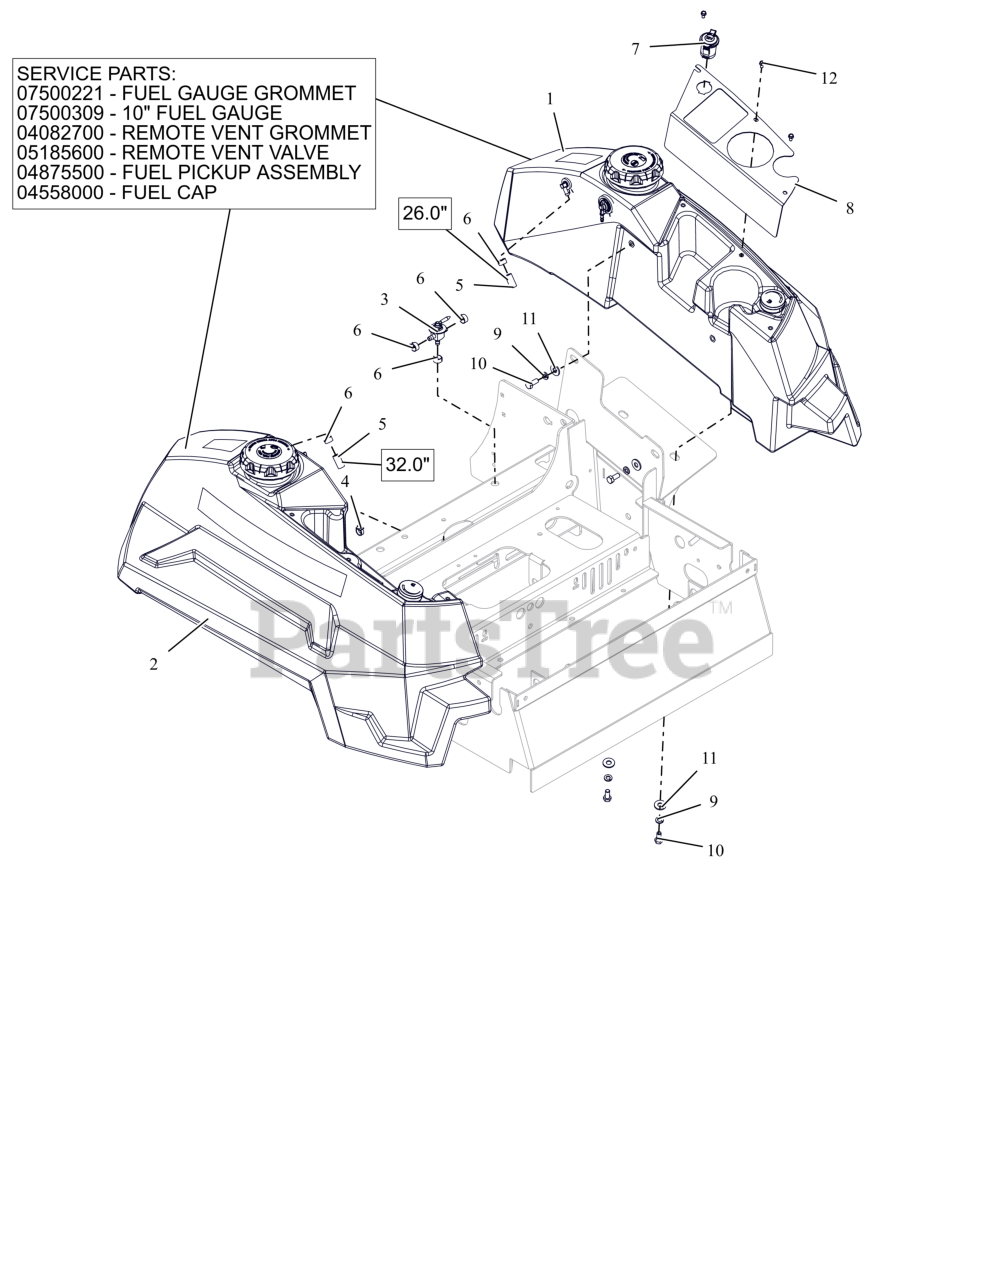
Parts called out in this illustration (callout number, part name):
1	ASM, LH FUEL TANK
1	GROMMET, FUEL GAUGE
1	GAUGE, REMOTE FUEL SEALED 10"
1	GROMMET, REMOTE VENT NITRILE
1	VALVE, COMBINATION VENT 3/16
1	ASSM,LRG TANK FUEL PICKUP LINE
1	CAP, FUEL VENTIN AUTOLOCK
2	ASSY-RH, PT400 FUEL TANK
3	VALVE - FUEL
4	ROUTING CLIP (1/2" ID)
5	HOSE, .25 LOW-PERM BULK GAS
6	CLAMP, FUEL LINE
7	PORT, 12 VOLT POWER
8	CUP HOLDER/POCKET PLATE - RED
9	WSHR,LK-REG .312X.078 ZCC
10	BLT,HEX .31-18X.75 G5 ZCC
11	WSHR,FLT .375X.875X.083 ZCC
12	SCR-MCH 10-24X.38 HWHSTAINLESS
